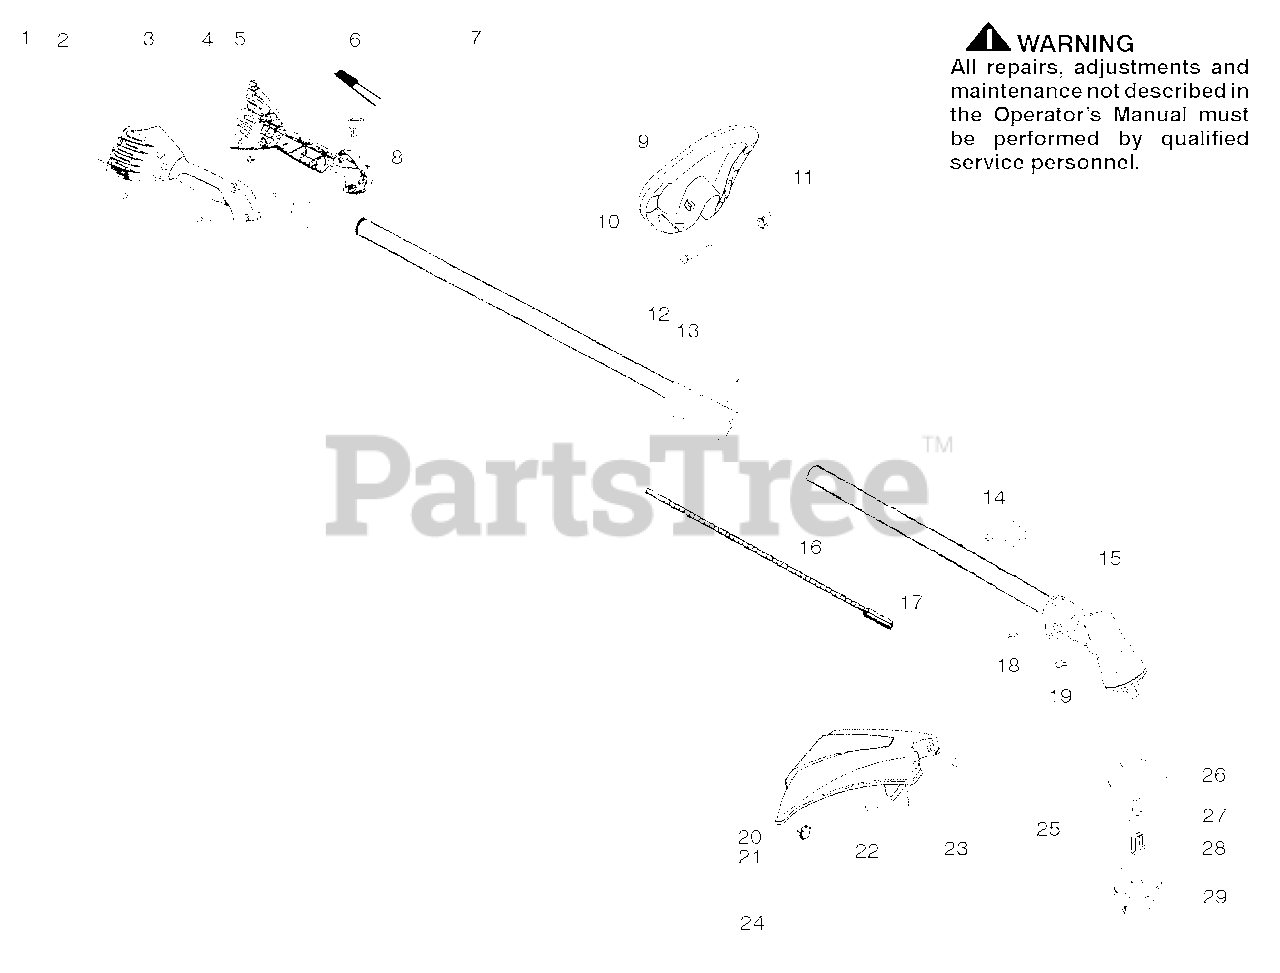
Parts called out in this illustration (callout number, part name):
1	Screw-alignment
3	Hsg.-Throttle-right
4	Screw-Cable Ret.
5	Hsg.-Throttle-left
8	Trigger-Throttle
9	Assy-Handle
11	Wingnut
12	Kit-Upper Shaft
14	Bracket-Shield
16	Shaft-Flex (lower)
17	Kit-Lower Shaft Assy.
23	Wingnut
24	Kit-Shield Assy.
25	Accy-Cutting Head
26	Assy-Hub/Arbor
27	Spring-Return
28	Retainer-Spool
29	Accy-Wound Spool
